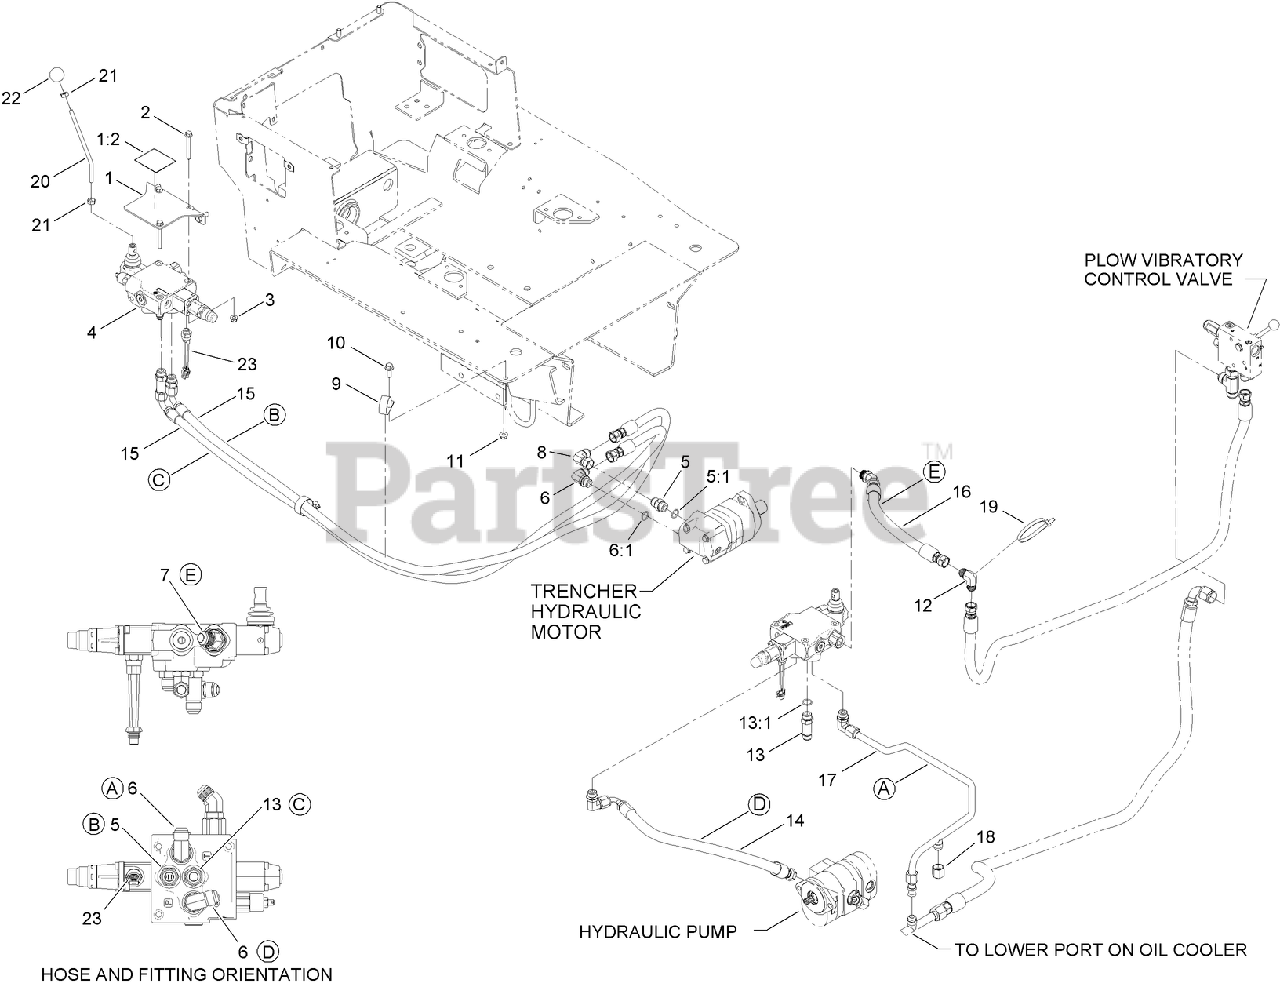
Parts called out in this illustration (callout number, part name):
1	TRENCHER BRACKET ASM
1:2	DECAL-CHAIN DIRECTION
2	SCREW-HHF
3	NUT-LOCK, HHF
4	VALVE-TRENCHER
5	FITTING-STRAIGHT
5:1	O-RING
6	FITTING-ELBOW, 90 DEG
6:1	O-RING
7	FITTING-ELBOW, 45 DEG
8	ADAPTOR
9	CLAMP-R
10	SCREW-HHF
11	NUT-HF, NI
12	FITTING-ELBOW, 90 DEG
13	FITTING-STRAIGHT
13:1	O-RING
14	HYD HOSE ASM
15	HYD HOSE ASM
16	HYD HOSE ASM
17	HYD TUBE ASM
18	FITTING-CAP
19	TIE-CABLE
20	LEVER-TRENCHER
21	NUT-HEX
22	KNOB-ROUND
23	SWITCH-BALL
